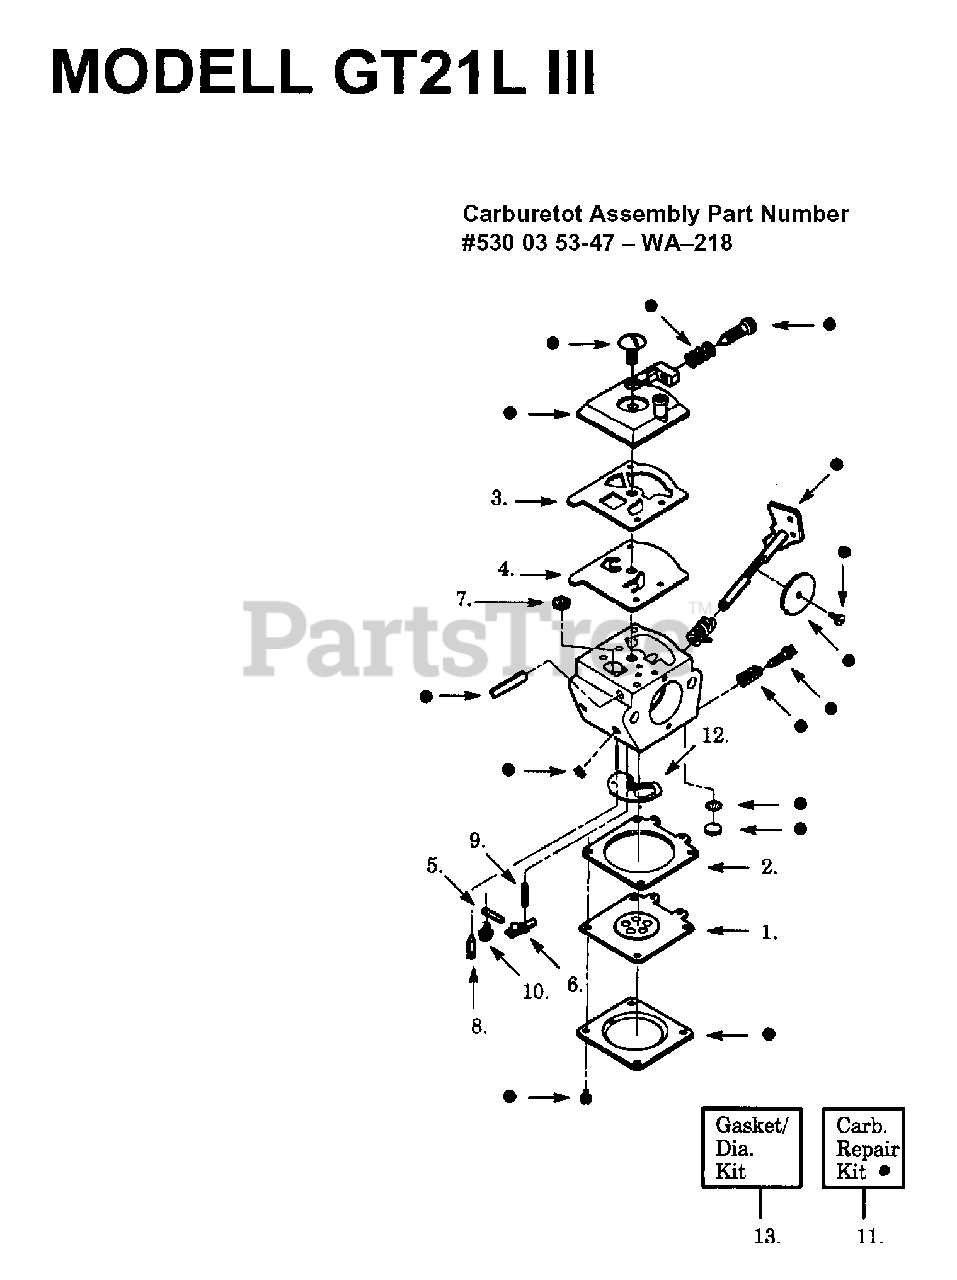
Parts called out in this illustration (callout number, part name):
1	METERING DIAPHRAGM
4	PUMP DIAPHRAGM
5	FULCRUM PIN
7	SCREEN-DUTCH TWILL INLE
8	VALVE/INLET.
9	METERING LEVER SPRING
11	CARBURETOR REPAIR KIT
13	CARB GASKET/DIAPH KIT
